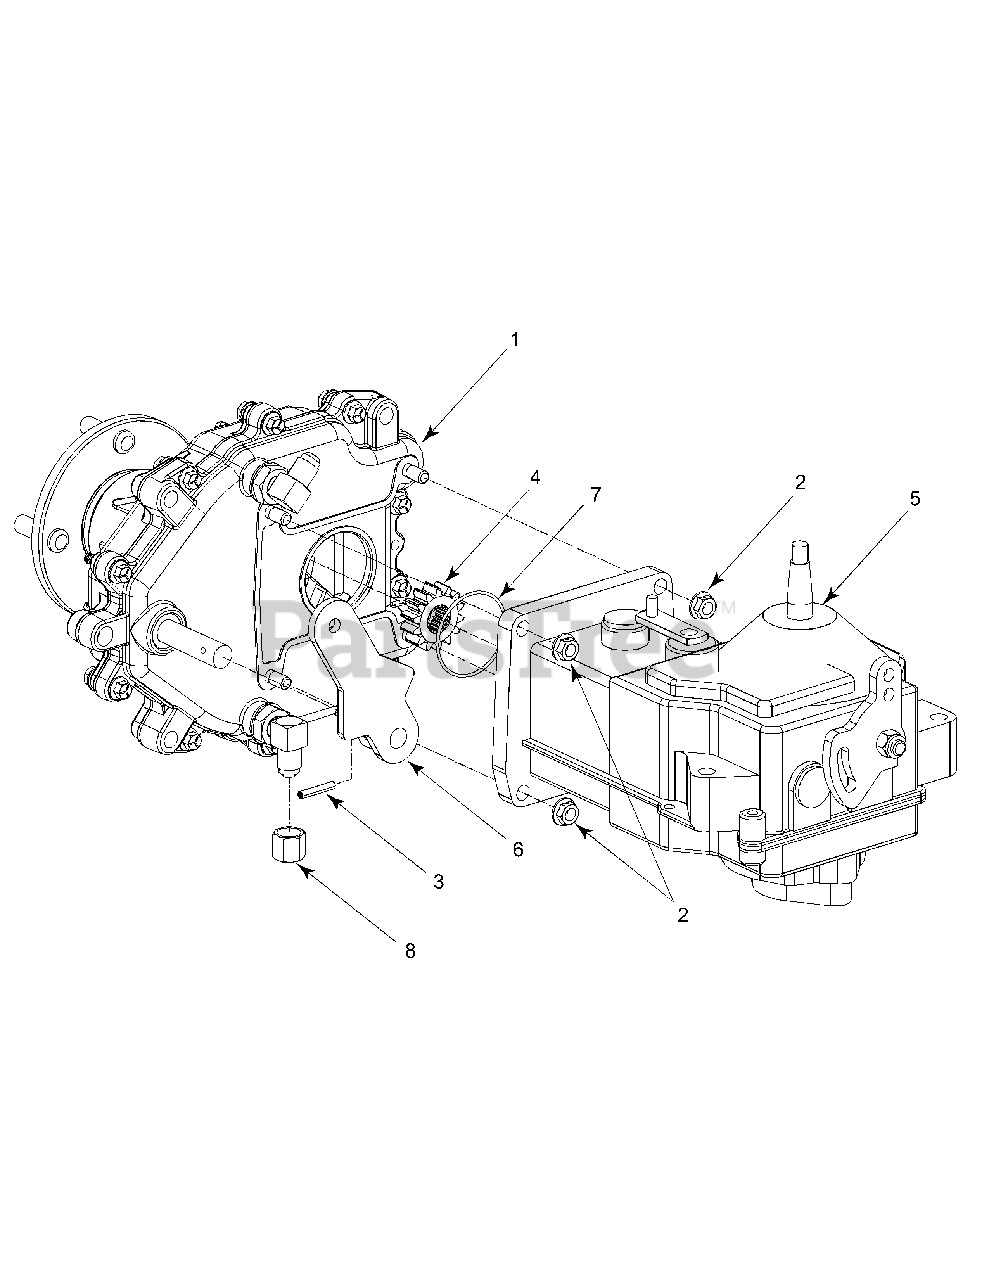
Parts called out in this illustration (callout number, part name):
1	Drive Ass’y Complete
2	Hex Flange Lock Nut 5/16-18
3	Spirol Pin 3/16 x 1.25
4	Spur Gear 14T
5	Hydro Transmission
6	Parking Brake Lever
7	O-Ring 2.0 Dia.
8	Cap Nut 3/8
